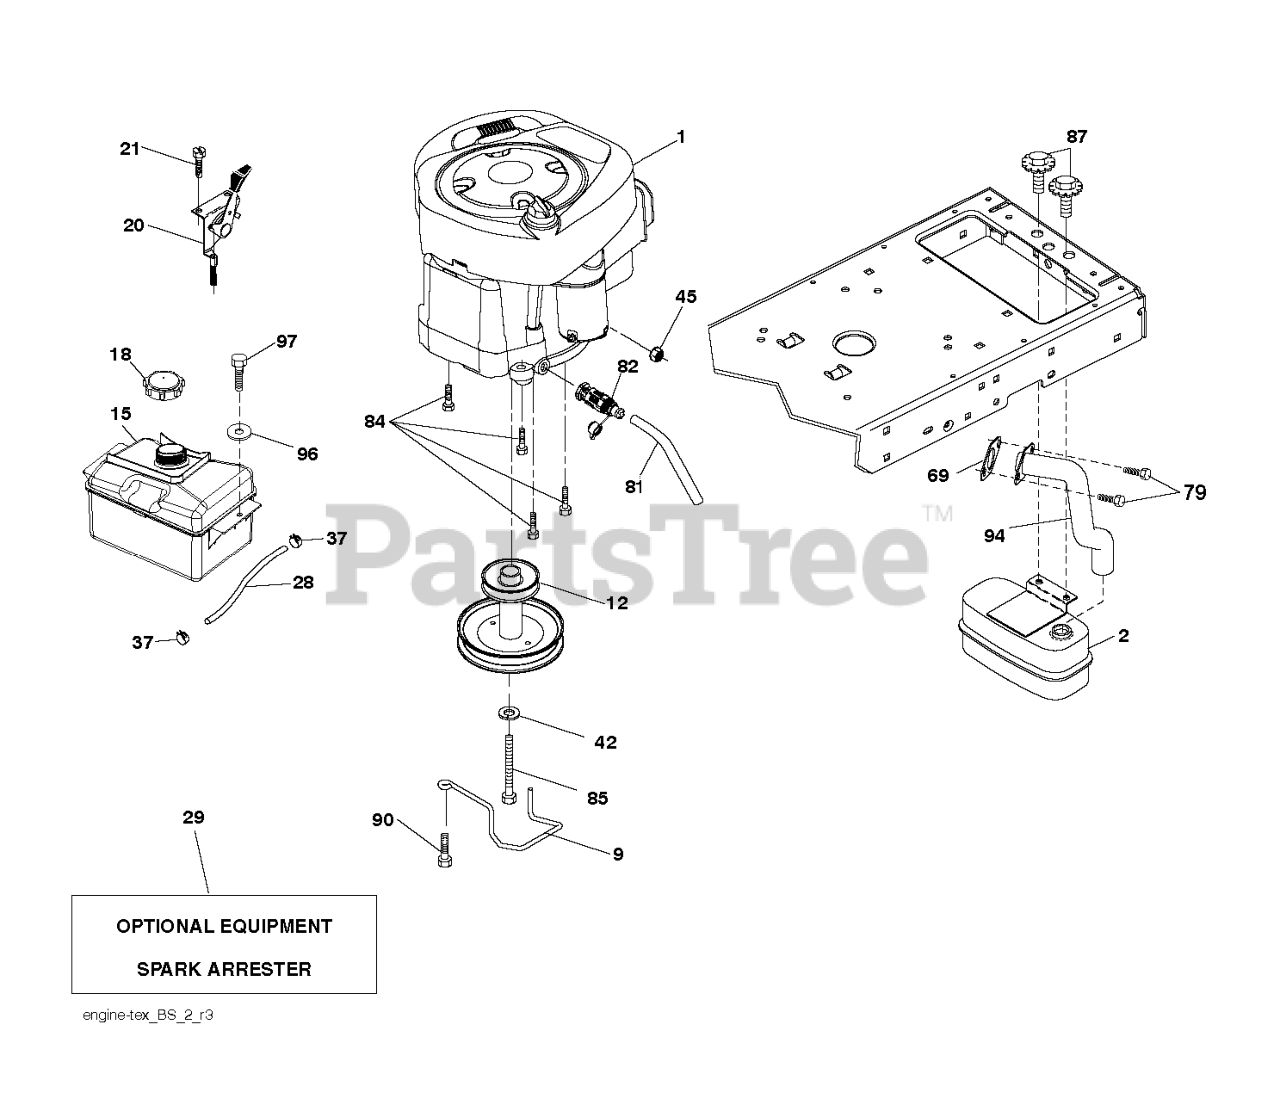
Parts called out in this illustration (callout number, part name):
2	MUFFLER.SINGLE.CYL.KOHL/B&S
9	KEEPER.BELT.ENGINE.4.2
12	PULLY ENGINE
15	TANK.ASM.FUEL.FR.2.5GA.
18	CAP ASM.FUEL.2.25"FR.
20	CONTROL.TH/CK.COBRA.KO
21	SCREW.#10 X 0.750.BOS
28	LINE.FUEL.20"FRONT.EMI
29	KIT.SPARK ARRESTOR 794945 B&S
37	HOSE CLAMP
42	LOCKWASHER
45	NUT
69	REPL BY 532 27 22-93
79	SCREW.SOCKET HD.5/16-1
81	TUBE, DRAIN OIL ASM.
82	VALUE.OIL.DRAIN
84	SCREW.3/8-16
85	BOLT HEX 7/16-20X4-1/4"
87	BOLT.5/16-18UNCX3/4 W/SEMS.BLK
90	SCREW 3/8-16X1
94	EXHAUST.TUBE.B&S.28/31
97	SCREW HEXWSHR 1/4-20X3/4
